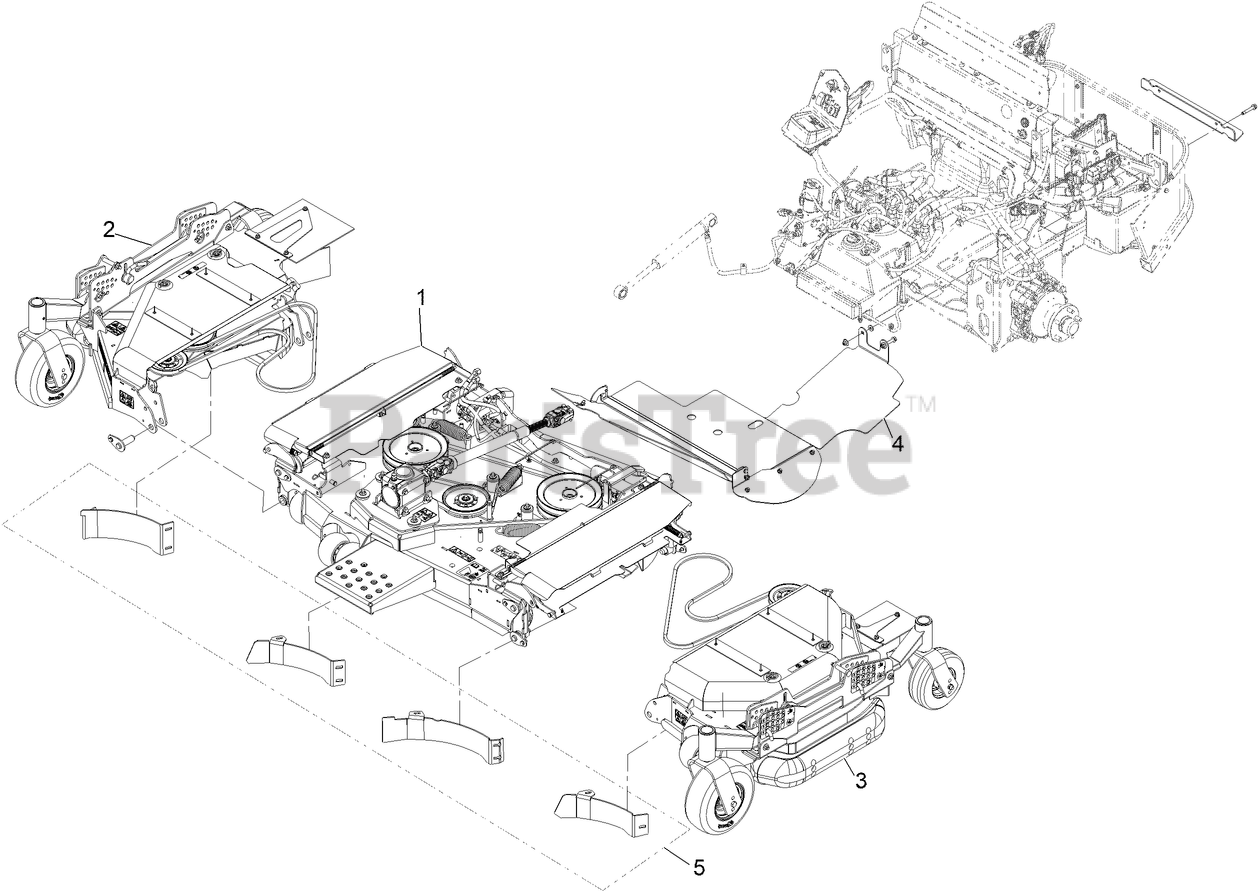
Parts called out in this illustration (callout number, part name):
1	ASM-DECK, CTR 96
2	ASM-DECK, RH WING 96
3	ASM-DECK, LH WING 96
4	Discharge Tunnel ASM
5	KIT-96RD MULCH
